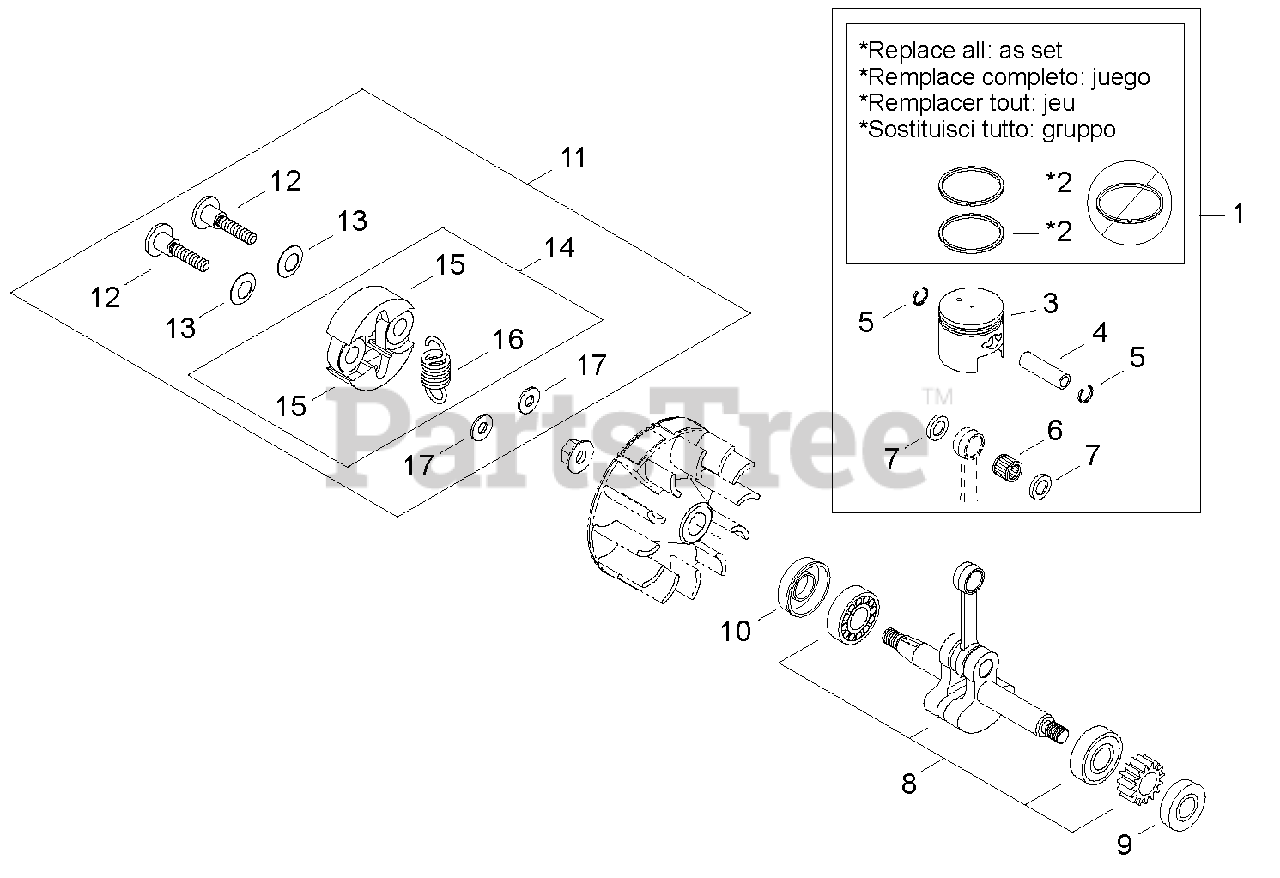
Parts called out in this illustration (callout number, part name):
1	PISTON KIT
2	RING, PISTON
3	PISTON
4	PIN, PISTON 10
5	RING, SNAP
6	BEARING, NEEDLE 10
7	WASHER, THRUST 10
8	CRANKSHAFT ASSY
9	SEAL, OIL 12
10	SEAL, OIL 12
11	CLUTCH ASSY
12	BOLT, CLUTCH
13	WASHER, SPRING
14	SHOE ASSY, CLUTCH
15	SHOE, CLUTCH
16	SPRING, CLUTCH
17	WASHER 6 MM
